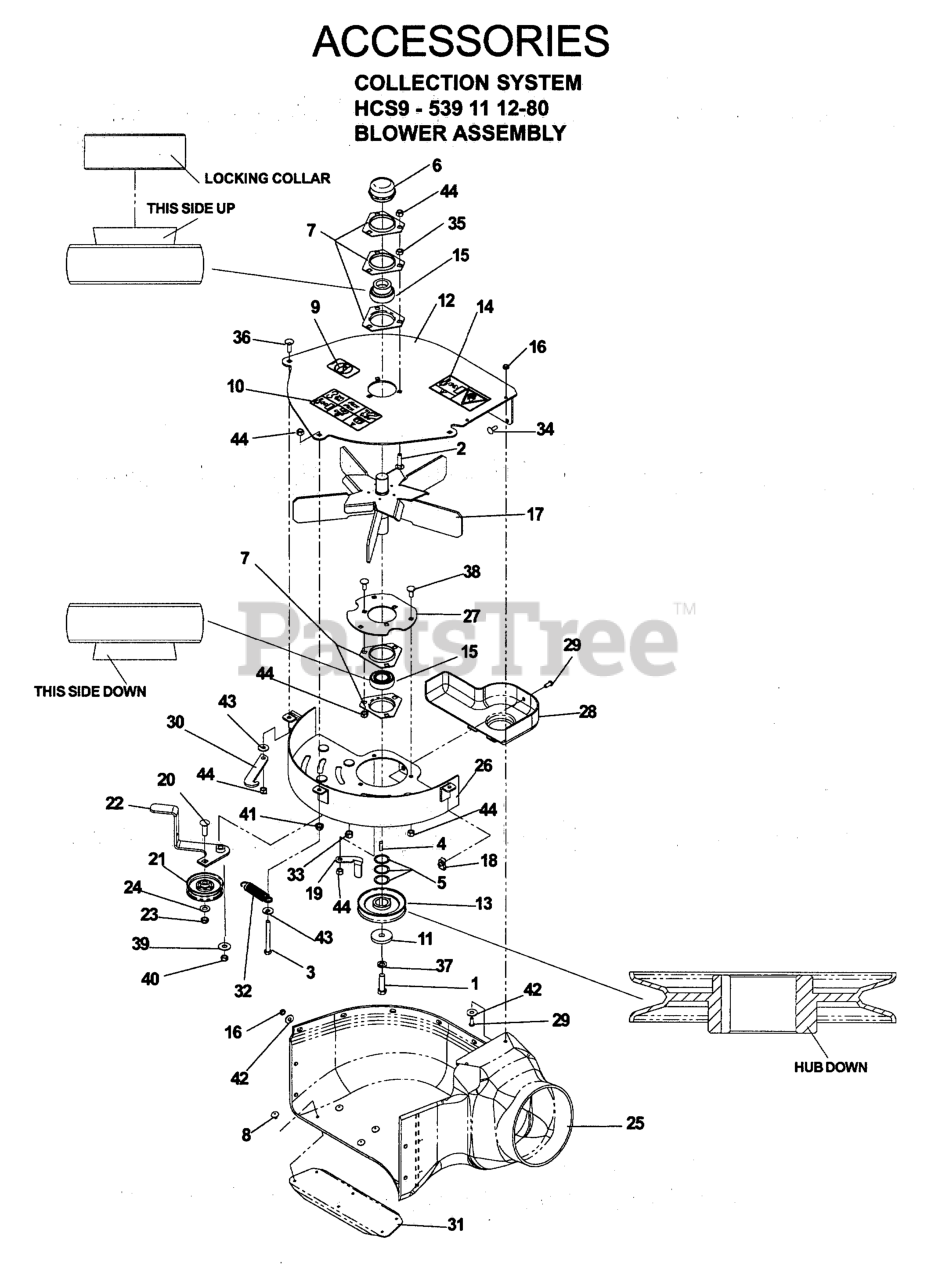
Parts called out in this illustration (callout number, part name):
1	HCS 7/16F X 1 1/2
2	BOLT, CARRIAGE 5/16X1-1/4
3	HCS 5/16C X 2-3/4
4	KEY 1/4 SQ X 3/4
5	BUSHING.MACHINE.18.GAUGE
6	GREASE CAP
7	BRG FLANGE
8	RIVET E/16 X 1/4 LG FLG
9	DECAL, NO STEP
10	DECAL, EURO WARNING
11	SPINDLE WASHER
12	FAN COVER W/DECALS
14	EURO DECAL, IMPELLER
15	BEARING KIT-2 PCS
16	JAM NUT 1/4C (2 2 PW01)
17	FAN WELDMENT
18	1/4C - U TYPE RETAINER
19	BELT GUIDE
20	RHSNB 3/8-16 X 1-1/4
23	NUT HEX 3/8-16 NYLON, THIN
24	WASHER 3/8 SAE FLAT
25	BLOWER HOUSING
26	FLOOR WELDMENT
27	BEARING PLATE
28	PULLEY SHEILD
29	SCR 1/4-20 X 5/8 BTN SKT HD ZD
30	KEEPER, IDLER
31	BLOWER SUPPORT
32	SPRING-TRANS
33	NUT 3/8-16 NYLOC
34	RHSNB 1/4C X 3/4
35	NUT 5/16C HEX
36	RHSNB 5/16C X 1
37	WASHER 7/16 LOCK
38	BOLT 5/16C X 3/4" CARRIAGE
39	WASHER 3/8 FLAT
40	NUT 3/8C CENTERBLOCK
41	NUT 5/16C WHIZ
42	WASHER 1/4 FLAT
43	WASHER 5/16 FLAT
44	NUT 5/16 NYLOC
